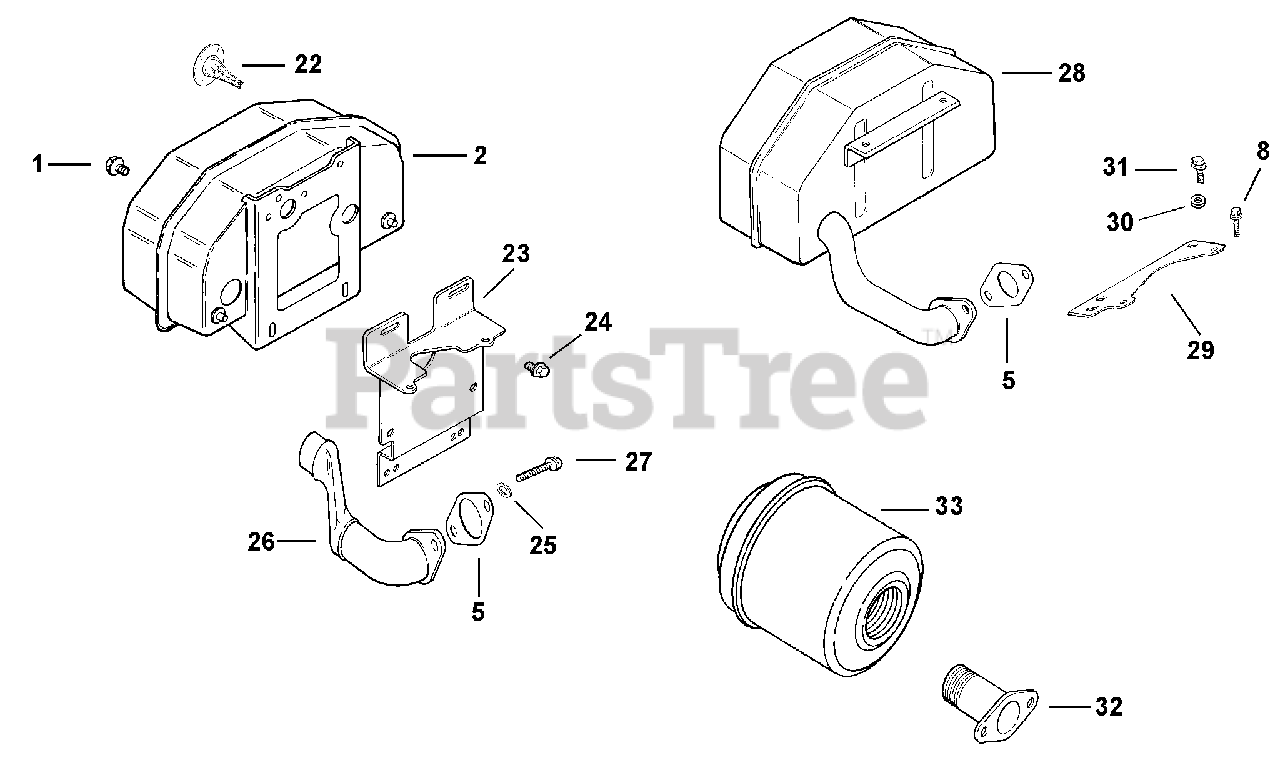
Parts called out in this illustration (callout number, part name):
5	GASKET, EXHAUST MANIFOLD
8	SCREW - USE M-645025
28	MUFFLER - DISCONTINUED
29	BRACKET - USE 12 126 71-S
30	WASHER, FLAT 1/4"
31	SCREW - USE M-639016
